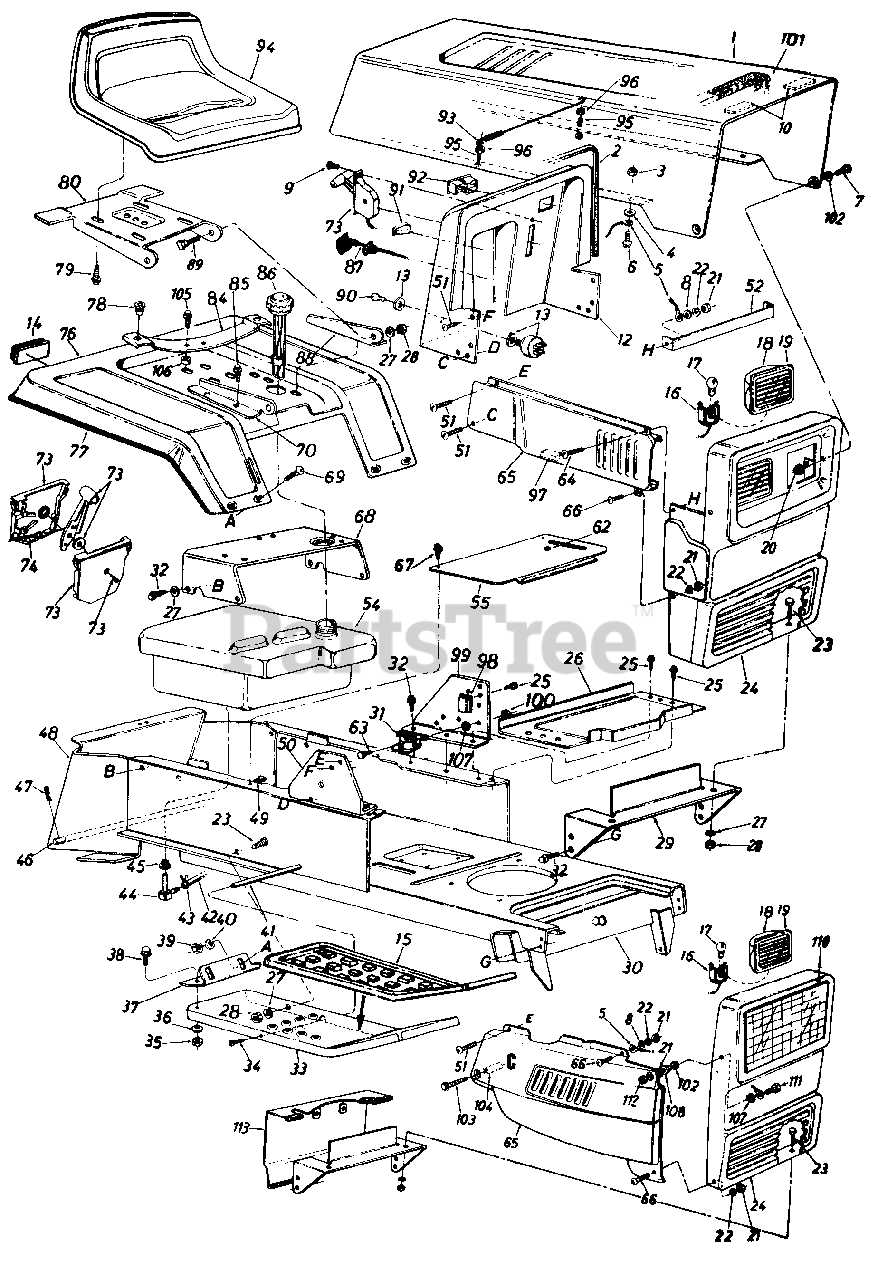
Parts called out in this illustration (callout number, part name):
3	Hex Sems Nut #10-24 Thd.
4	Fl-Wash. .20" I.D. x.41" O.D.
5	Hood Stop
6	Truss Scr. #10-24 x .5"
7	Shld. Bolt .375 Dia. x .125t
8	Fl-Wash. 1/4" I.D.
9	Truss Mach. AB-Tap Scr. #10-24 x .5" Lg.
10	Foam Strip
14	Reflector
15	Rubber Foot Pad
16	Socket
17	Lamp
18	Headlight Housing
19	Lens
20	L-Nut 1/4-28 Thd.
21	Hex Nut 1/4-20 Thd.
22	L-Wash. 1/4" I.D.
23	Hex Bolt 5/16-18 x .75" Lg.
24	Grille
26	N Battery Plate
27	L-Wash. 6/16" I.D.
28	Hex Nut 5/16-18 Thd.
29	Grille Mounting Bracket
30	N Lower Frame Ass'y.
31	Solenoid
32	Hex Thd. Rolling Scr. 5/16-24 x .75" Lg.
35	Hex Nut 5/16-18 Thd.
36	Bell-Wash..34" I.D.
39	Hex Nut 1/4-20 Thd.
40	L-Wash. 1/4 " I.D.*
41	Running Board Rod
42	Fuel Line 46" Lg.
43	Hose Clamp
44	90ø Elbow
45	Bushing
46	Hitch Rod
47	Internal Cotter Pin
50	Dash Support Brkt. R.H.
51	Hex Tap Scr. 1/4 x .75" Lg.
52	Tie Strap Grille Side Panel
54	Fuel Tank
55	Transmission Cover Ass'y.
62	Snap Bushing
63	Hex Bolt 1/4-20 x .50" Lg.*
64	Truss Hd. Scr. 1/4-20 x .75"
67	Truss B-Tap Scr. #10 x .5"
68	Seat Mounting Channel
69	Carriage Bolt 1/4-20 x .50"*
70	Seat Bracket R.H.
73	Throttle Control Box Ass'y.
74	Throttle Control Wire
78	Grommet
79	Hex AB-Tap Scr. 3/8 x .75"
80	Seat Pivot Bracket
84	Seat Spring
85	Hex Self-Tap Scr. 5/16-18 x .5"
86	Gas Cap w/Gauge
87	Choke Control Comp.
88	Seat Bracket L.H.
89	Shld. Bolt .437" Dia. x .162"
90	Ignition Key
91	Light Switch
92	Ammeter
93	Hood Spring
94	Seat Ass'y.
95	Hex Bolt #10-24 x 1.0" Lg.
96	Hex Sems Nut #10-24
97	Rubber Strip 1/2 " Sq . x 21/2 "
98	Circuit Breaker
99	Dash Support Brkt. L.H.
100	Hex Sems Nut 1/4-20 Thd.
101	PVC Foam
102	Washer .34" I.D. x .62" O.D.
103	Hex Tap Scr. 1/4-20 x 1.75
104	Spacer.255" I.D.
105	Hex Tap Scr. 5/16-18 x 1.25"
106	Spacer.38" I.D.
107	Ext. L-Wash. 1/4" I.D.
108	Shld. Spacer .125" Lg.
110	Headlight Bezel
111	Hex Bolt 1/4-20 x .88" Lg.
112	Acorn Nut 1/4-20 Thd.
113	Baffle Ass'y. Comp.
